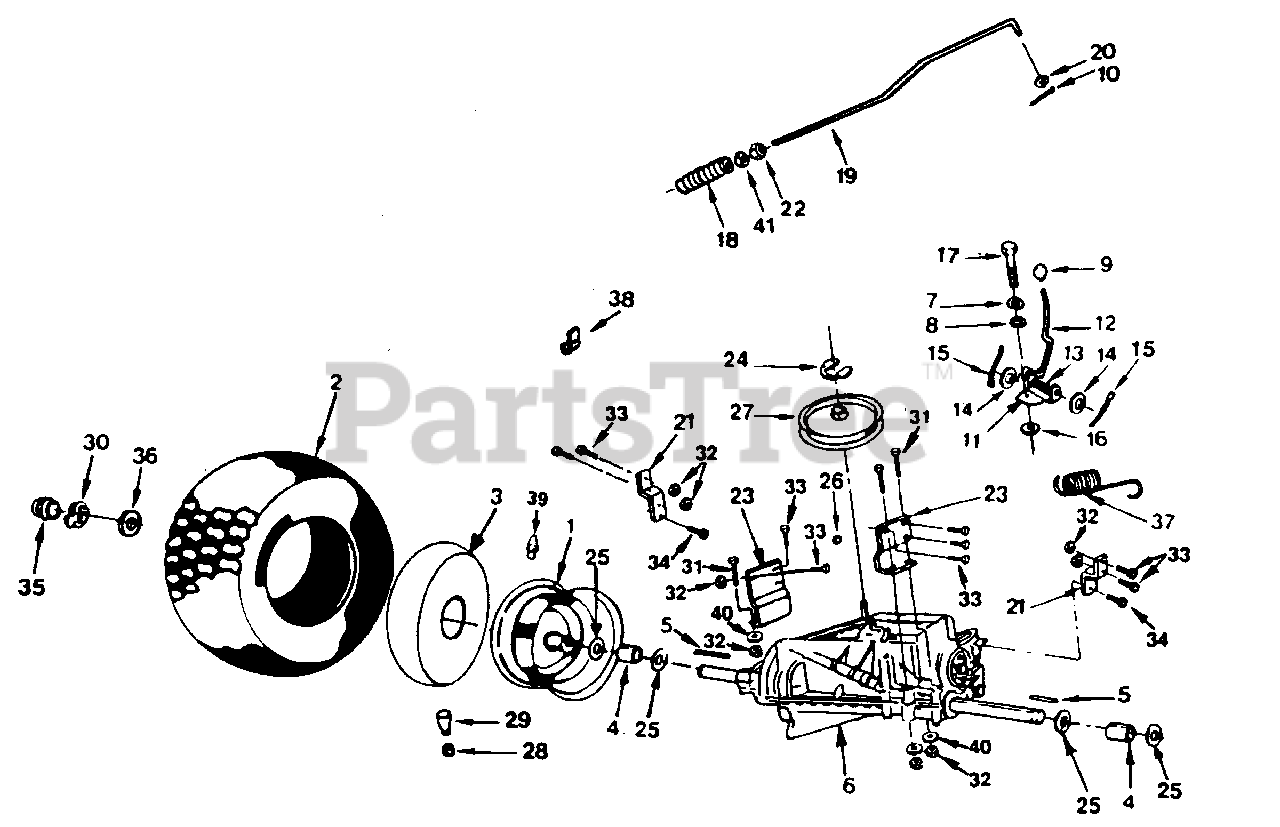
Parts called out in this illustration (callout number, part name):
1	Rear Rim Assembly (AYP part number)
2	Tire (Tubeless) (AYP part number)
3	Tire Tube (Not furnished with Tractor) (AYP part number)
4	Split Spacer (AYP part number)
5	Square Key (AYP part number)
6	6-speed Foote Dana Transaxle (Model No. 4360-7) (AYP part number)
7	Lock Washer 1/4 (AYP part number)
8	Washer (AYP part number)
9	Control Knob (AYP part number)
10	Cotter Pin (AYP part number)
11	Shift Rod Plate (AYP part number)
12	Shifter Rod (AYP part number)
13	Torsion Spring (AYP part number)
14	Washer (AYP part number)
15	Cotter Pin 1/8 x 1 (AYP part number)
16	Shift Plate Washer (AYP part number)
17	Hex Bolt (AYP part number)
18	Brake Rod Spring (AYP part number)
19	Brake Rod (AYP part number)
20	Washer 13/32 x 13/16 x 16 Ga. (AYP part number)
21	Torque Strap (AYP part number)
22	Jam Hex Nut (AYP part number)
23	Transaxle Bracket (AYP part number)
24	Retainer Ring (AYP part number)
25	Washer (AYP part number)
27	Transaxle Input Pulley (AYP part number)
28	Valve Cap (AYP part number)
29	Valve Stem (AYP part number)
30	E-Ring (AYP part number)
31	Hex Bolt 3/8-16 x 2-3/4 (AYP part number)
32	Nut
33	Hex Bolt 3/8-16 x 3/4 (AYP part number)
34	Thd. Form Washer Hd. Hex Screw
35	Rear Hub Cap (AYP part number)
36	Washer (AYP part number)
37	Brake Return Spring (AYP part number)
38	Fuel Line Clip (AYP part number)
39	Grease Fitting (AYP part number)
40	Washer (AYP part number)
41	Locknut (AYP part number)
